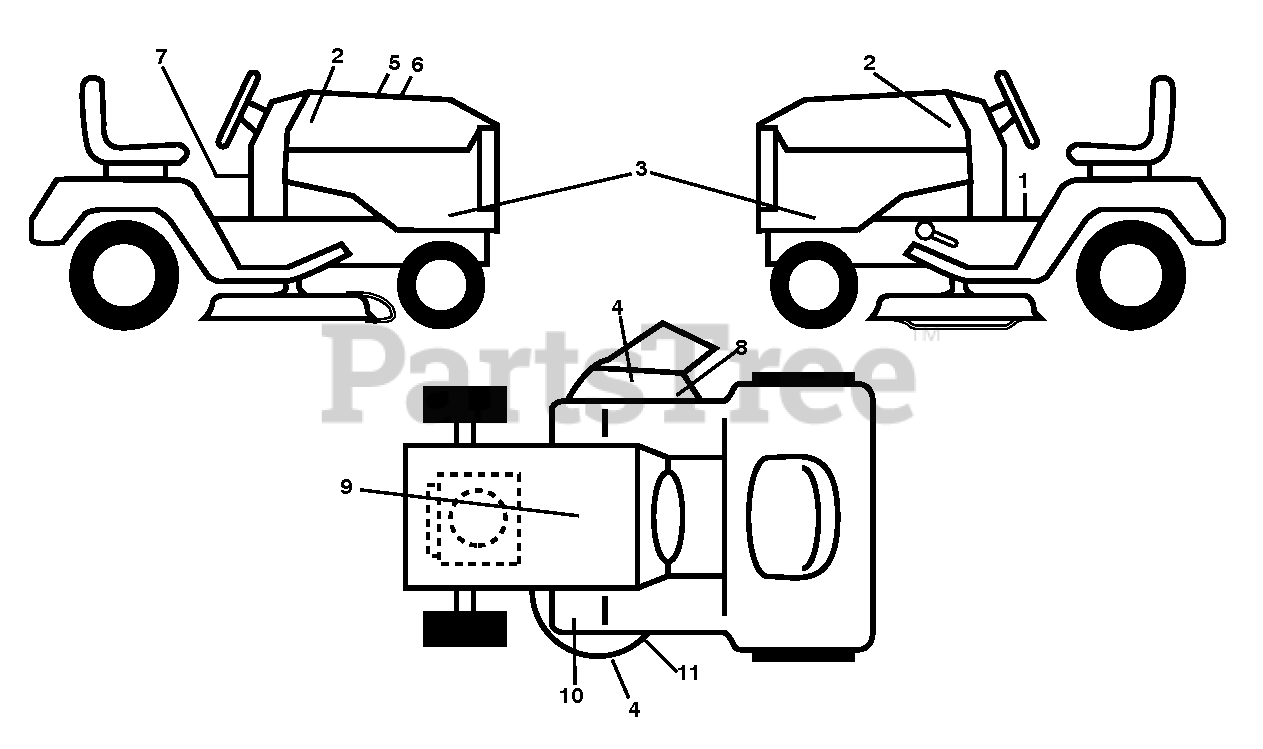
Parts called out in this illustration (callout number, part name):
1	DECAL.WARNING.2007.ENG/FR
2	DECAL.BADGE.170MM.TEXTLOGO.
3	DECAL.SDPNL.GT2.YT42XLS.SET
4	DECAL.DECK.6MIL.EURO.NOSTEP
5	DECAL.WARNING.CUST.RESP.E85.
7	DCL.WARNING.SPARK.IGNITION.CA
8	DECAL.DECK.6MIL./DEF.SHLD.WARN
9	DECAL BTRY SYMBOLS
10	DECAL.PEDAL.HUSQ.CROWN
11	DECAL.MOWER.SCH.48/54.PREM
